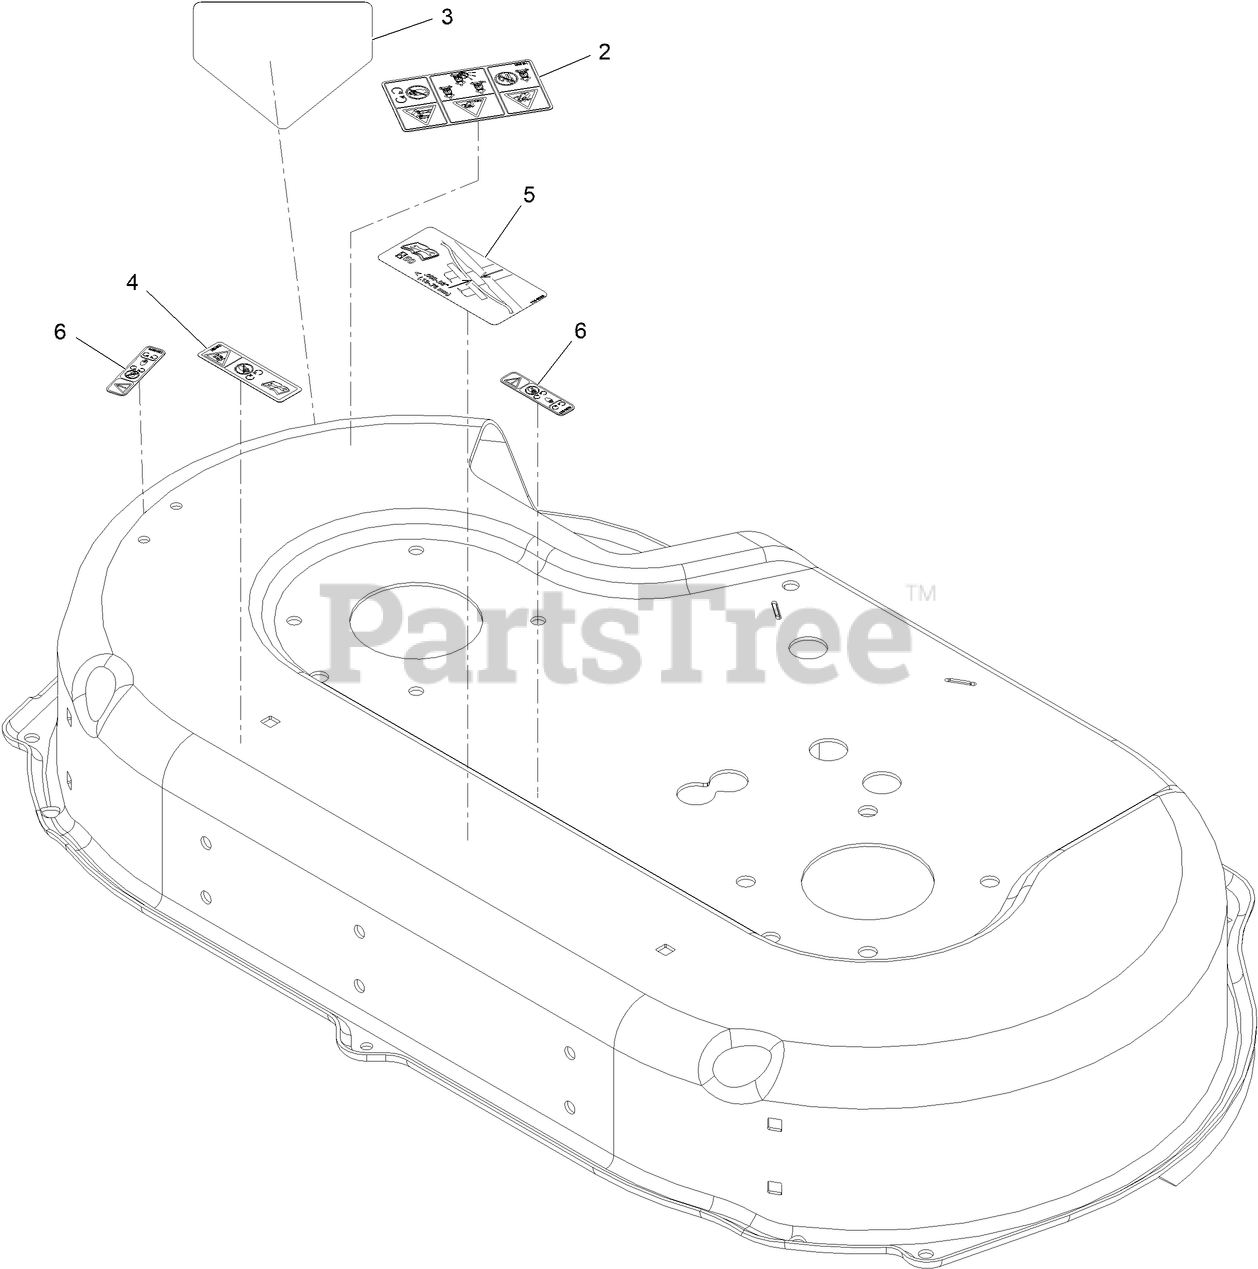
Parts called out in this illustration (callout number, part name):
2	DECAL-DANGER, CE
3	DECAL-DANGER
4	DECAL-WARNING
6	DECAL-WARNING
